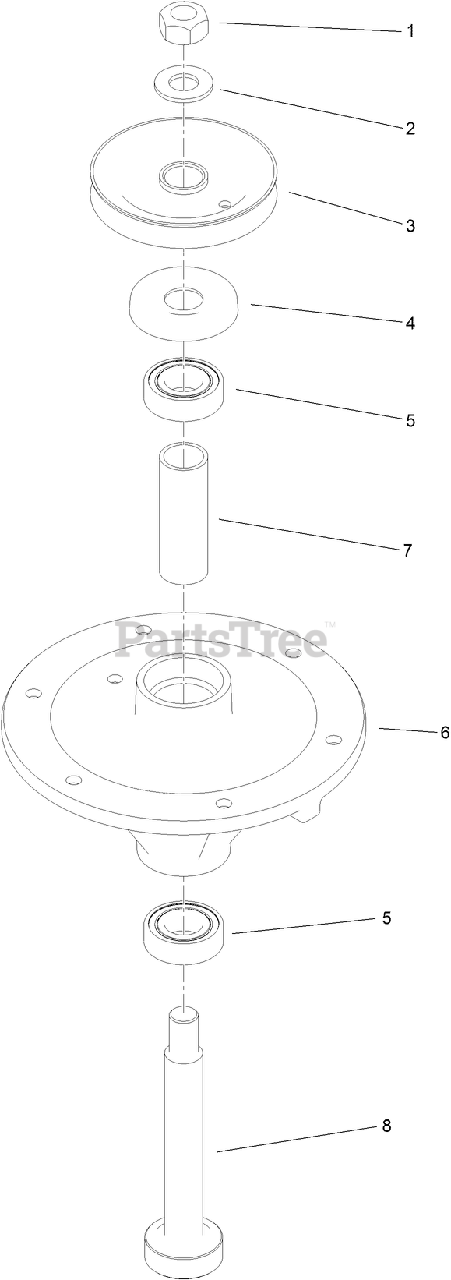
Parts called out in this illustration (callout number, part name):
1	NUT-HEX
2	WASHER
3	PULLEY ASM
4	SHIELD-BEARING
5	BEARING-BALL
6	HOUSING-SPINDLE
7	SPACER-BEARING
8	SHAFT-SPINDLE
